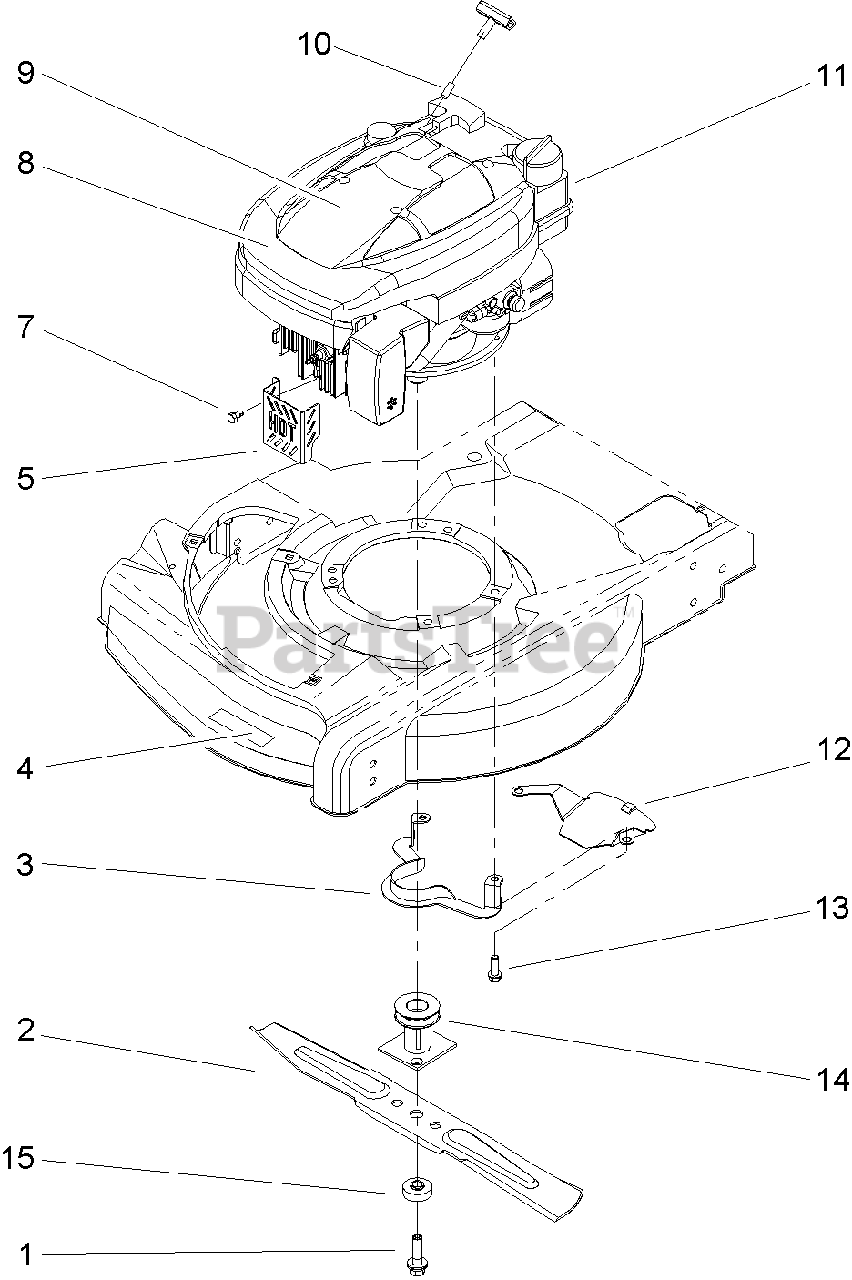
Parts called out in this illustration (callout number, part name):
1	BOLT-BLADE
3	GUIDE-BELT
4	DECAL-DECK
5	GUARD-MUFFLER
7	SCREW-HWH
8	APPLIQUE
9	DECAL-RECOIL
10	STOP-ROPE
12	SHIELD-GRASS
13	SCREW-TAPTITE
14	DRIVER-BLADE
